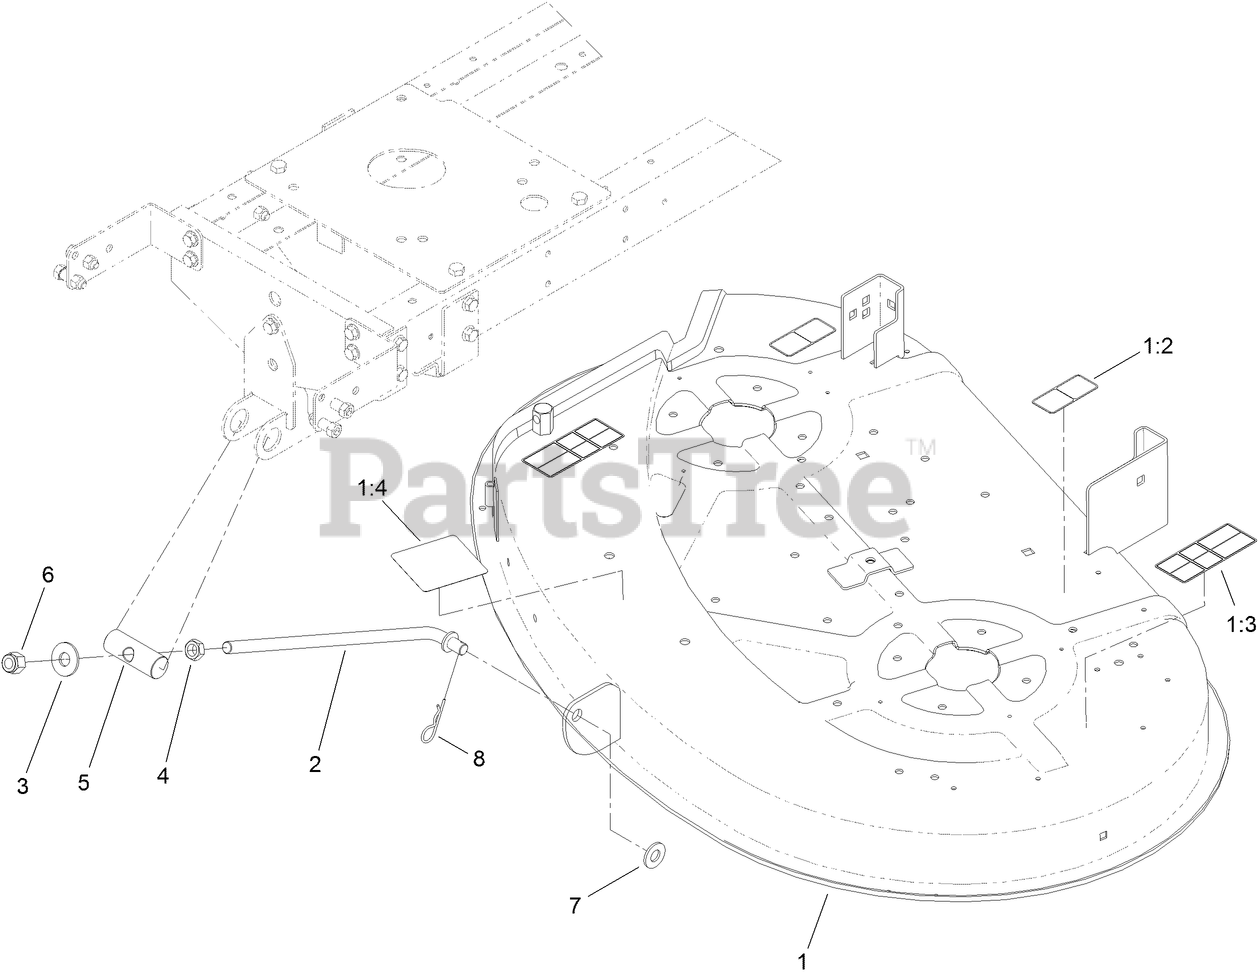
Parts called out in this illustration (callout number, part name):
1:2	DECAL-WARNING
1:3	DECAL-WARNING
1:4	DECAL-GUIDE, BELT
2	ROD-PIVOT
3	WASHER-FLAT
4	NUT-JAM
5	PIN-PIVOT
6	NUT-HEX
7	WASHER-THRUST
8	PIN-HAIR
